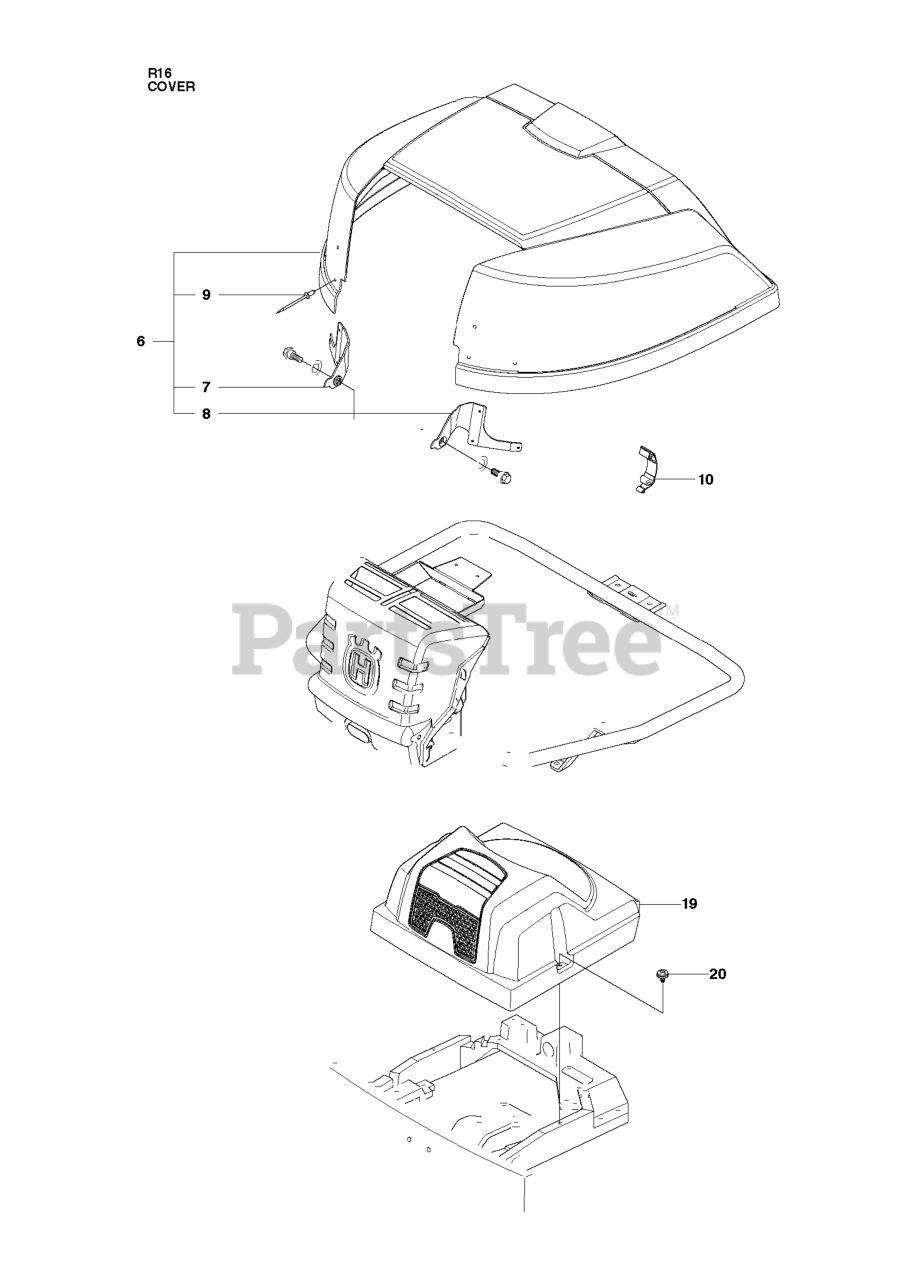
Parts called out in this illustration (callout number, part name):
7	HINGE LEFT
8	HINGE RIGHT
10	BUCKLE ORANGE
19	RP COVER
